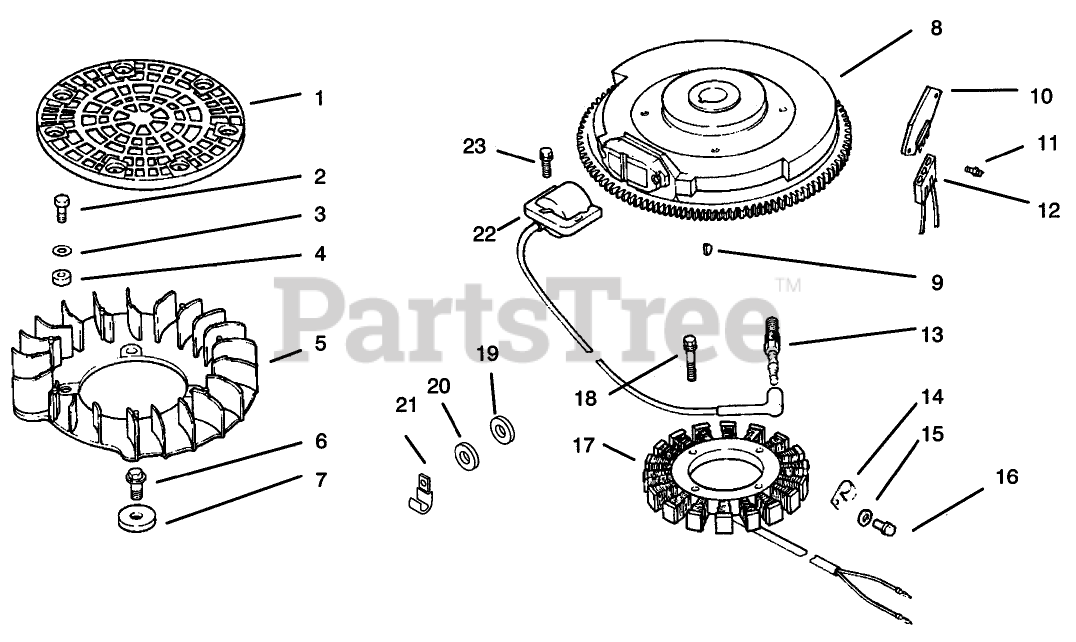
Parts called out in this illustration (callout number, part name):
1	Screen-Grass (Only On: 72103, 72083)
2	Screw
3	Washer
4	Spacer-Fan (Only On: 72103)
5	Fan (Only On: 72103, 72083)
6	Screw
7	Spacer-Fan
8	Flywheel ASM (Only On: 72103, 72083)
9	Key
10	Rectifier-Regulator
11	Screw
12	Connector
13	Spark Plug
14	Clip
15	Washer
16	Screw
17	Stator-15 amp
18	Screw
19	Washer
20	Washer
21	Clip
22	Module-Ignition
23	Screw
